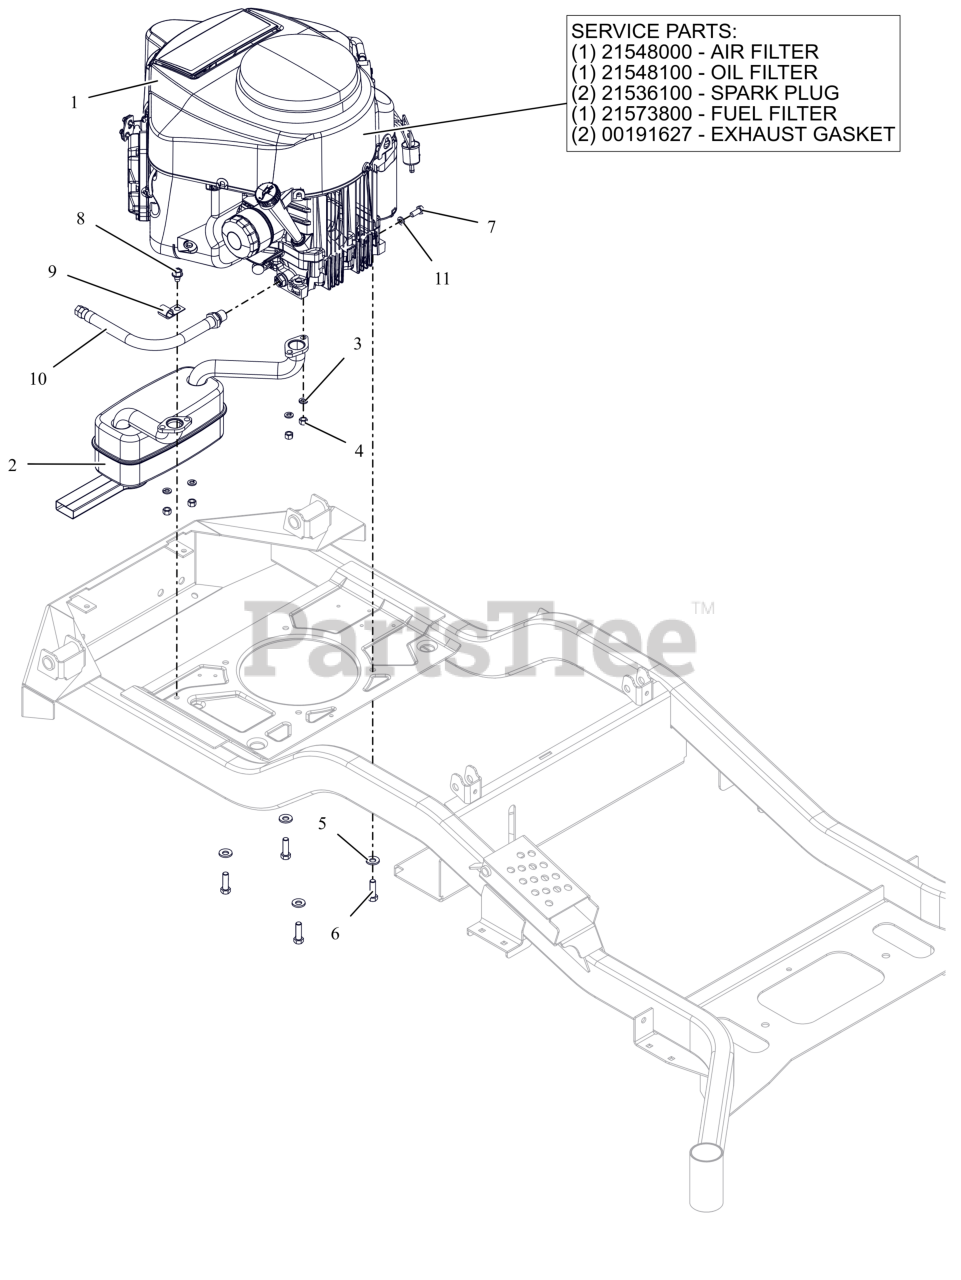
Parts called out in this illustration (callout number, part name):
1	ENGINE, KAWASAKI FR730 24HP
1	AIR FILTER, KAWASAKI FR
1	OIL FILTER, KAWASAKI FR
1	PLUG, SPARK
1	FUEL FILTER-KAWASAKI FR
1	GASKET, MUFFLER S/O
2	MUFFLER, KAWASAKI
3	WSHR,LK-REG .312X.078 ZCC
4	NUT-LK-TOP-FLG M8 ZCC
5	WASHER, 3/8" SPRING DISC
6	BLT, HEX .38-16X1.25 G5 ZCC NT
7	BLT, HEX M8-1.25X20 G8.8 ZCC
8	SCR,TAP .375-16X.50 HWH TR ZCC
9	J-CLAMP
10	HOSE, OIL DRAIN
11	WSHR,LK-REG .312X.078 ZCC
